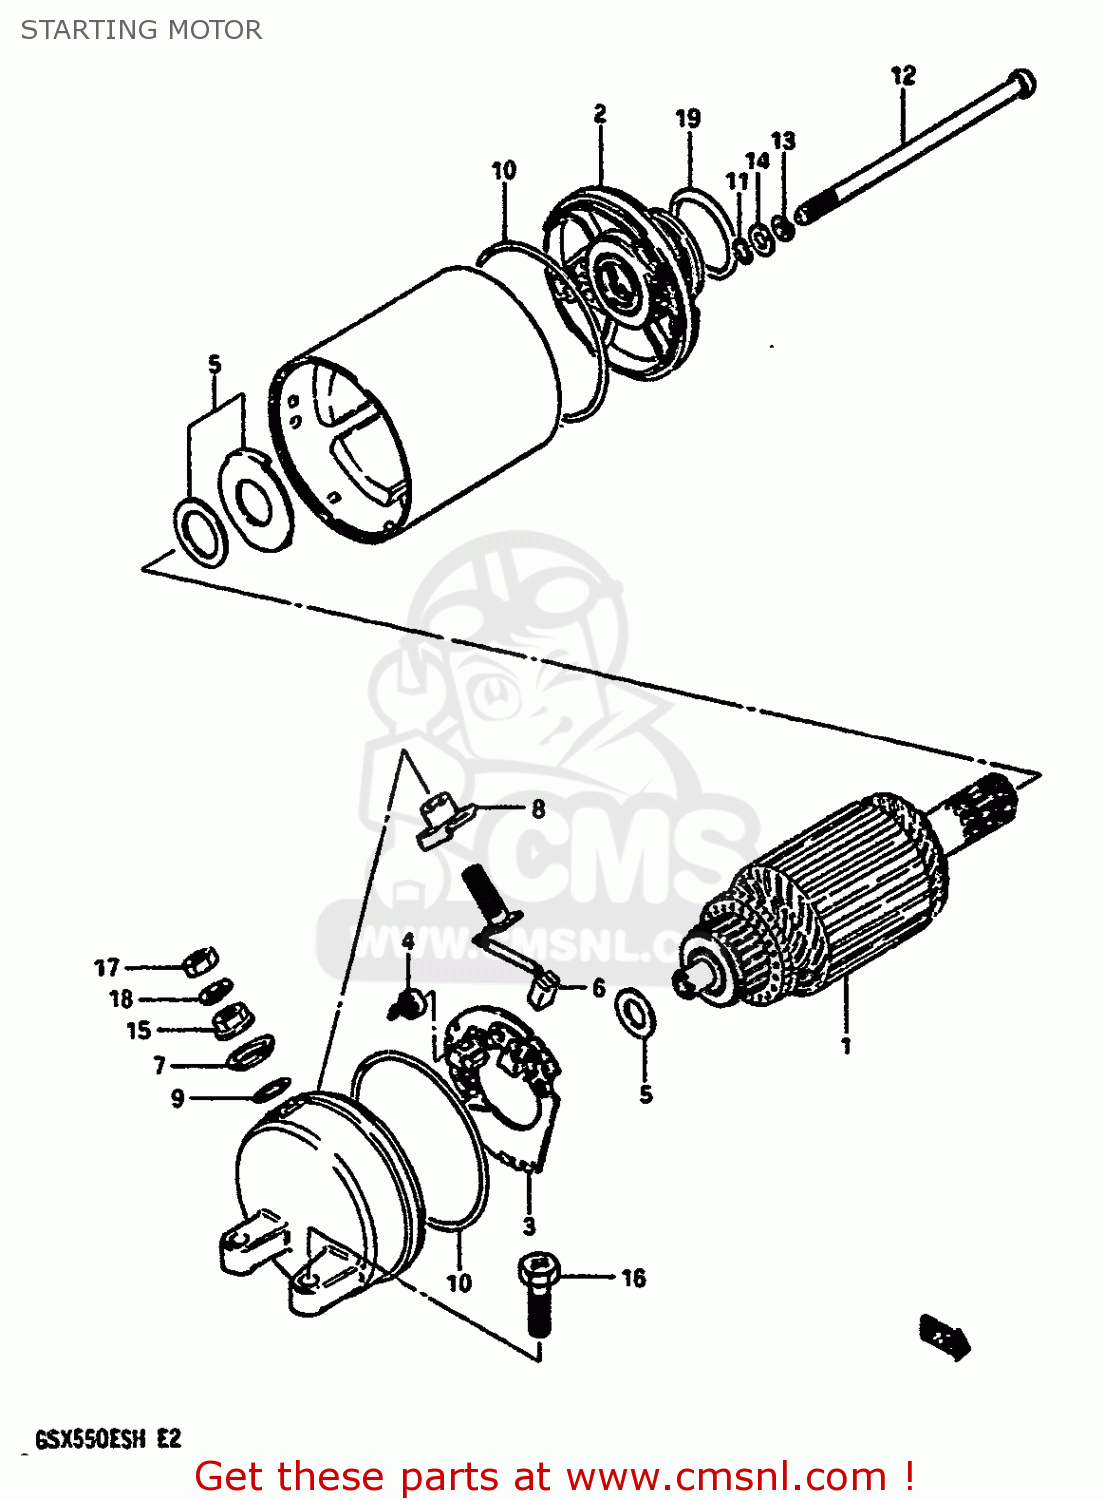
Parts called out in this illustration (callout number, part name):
1	ARMATURE
2	BRACKET SET,STARTING MOTOR
3	HOLDER,BRUSH
4	SPRING
5	SHIM SET,STARTING MOTOR
6	BRUSH SUB ASSY,STARTING MOTOR
7	BUSHING
8	BUSH,B
9	O RING
10	O RING
11	O RING
12	BOLT
13	LOCK WASHER
14	WASHER
15	NUT
16	BOLT
17	NUT
18	WASHER,LOCK
19	O RING(D:3,ID:24.5)
